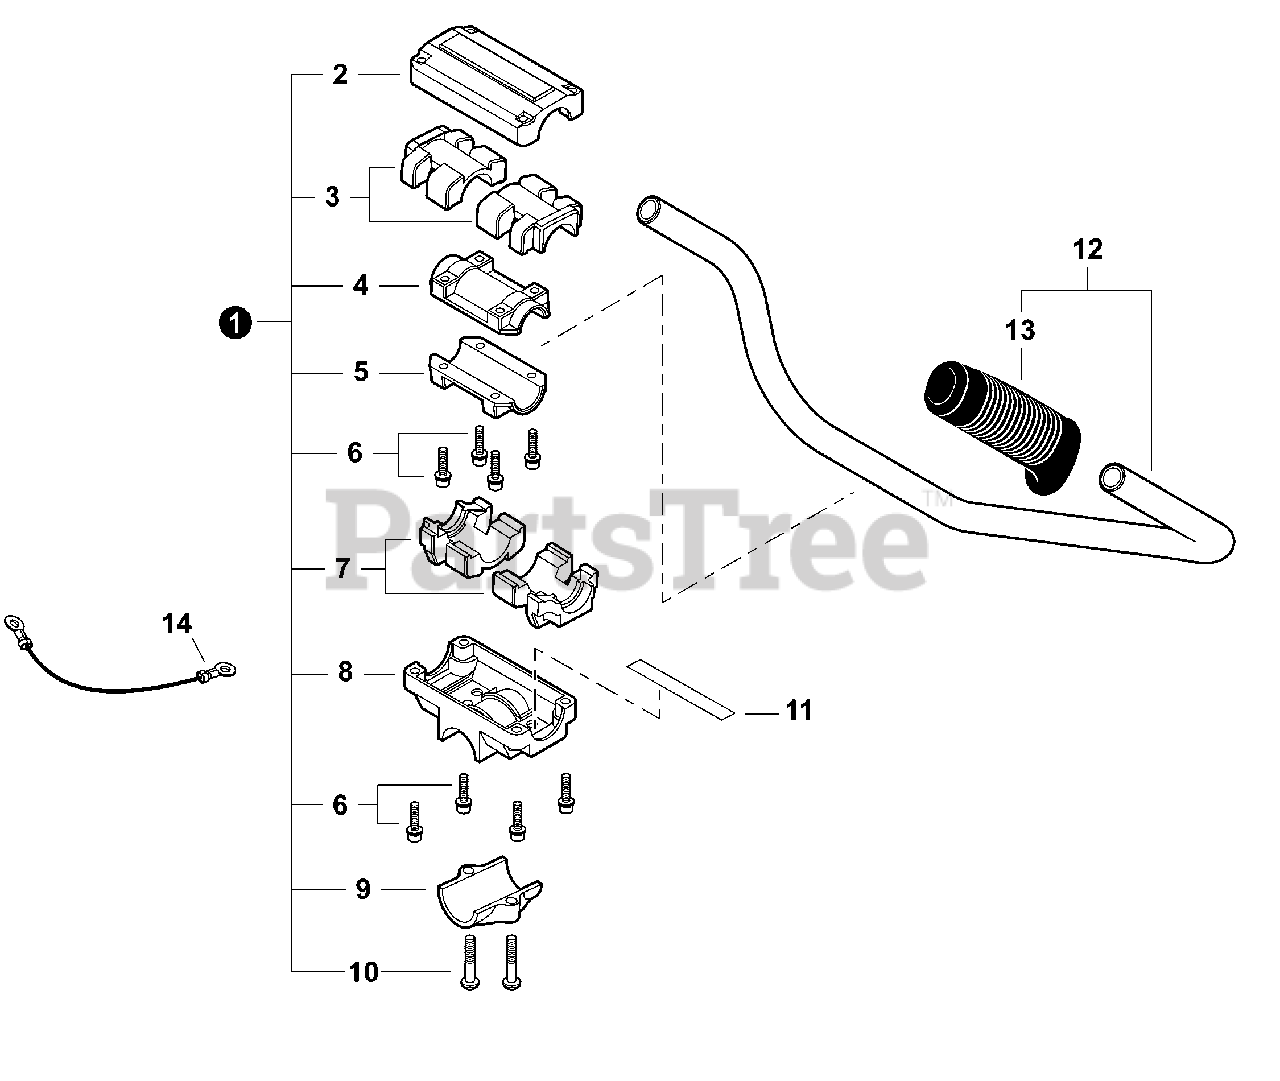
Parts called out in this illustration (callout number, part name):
1	BRACKET KIT, HANDLEBAR
2	CLAMP, UPPER
3	CUSHION, UPPER
4	CLAMP, UPPER
5	CLAMP, LOWER
6	BOLT M5x25
7	CUSHION, LOWER
8	BRACKET, HANDLE 28
9	CLAMP, LOWER 28
10	SCREW M6x25
11	LEAD - GROUND
12	HANDLEBAR ASSY
13	GRIP
14	LEAD - GROUND
